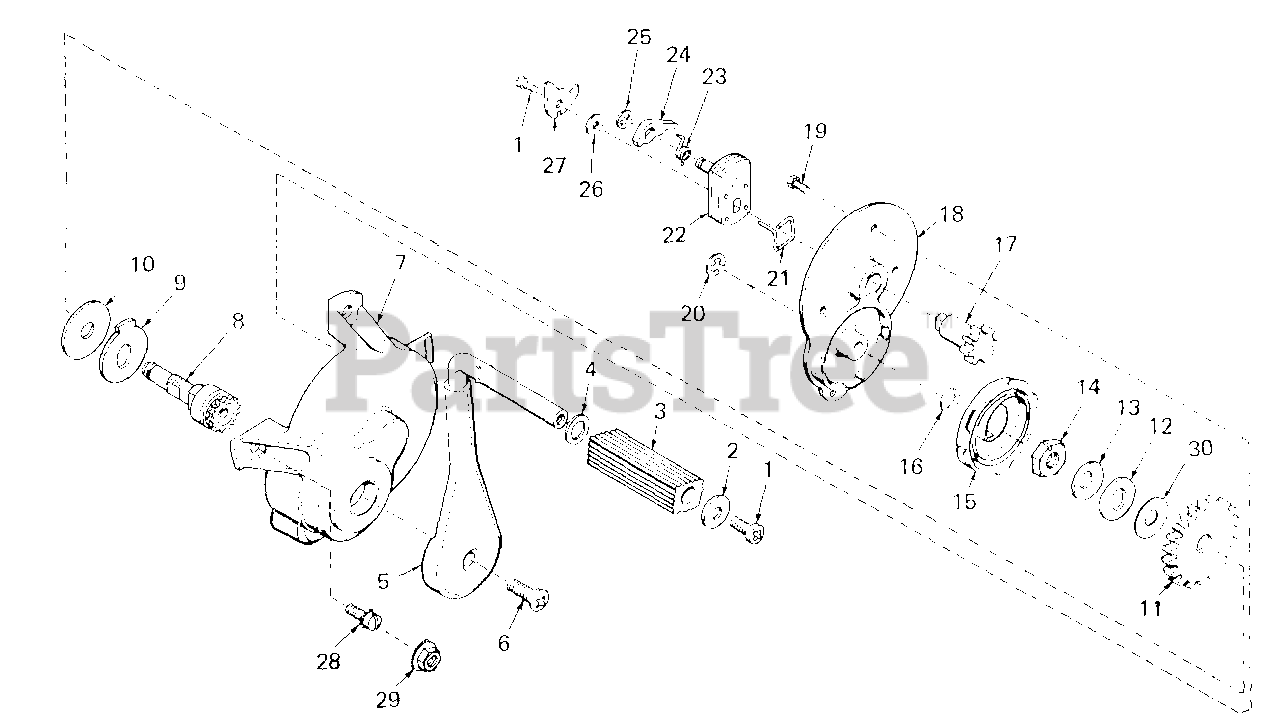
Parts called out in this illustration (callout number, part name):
1	Screw, 1/4-20 x 5/8"
5	Arm Assy., Crank & Kick
7	Housing Assy., Starter
9	Plate, Clutch
10	Liner, Clutch
13	Washer, Belleville
15	Spring & Keeper Assy.
18	Cover Assy., Starter
19	Screw, 1/4-20 x 1/2"
20	Ring, Retainer
21	Spring, Brake
22	Plate & Pin Assy., Dog
23	Spring, Dog
25	Ring, Retainer
27	Cam, Dog
28	Screw, 1/4-28 x 9/16"
29	Nut, 1/4-28
